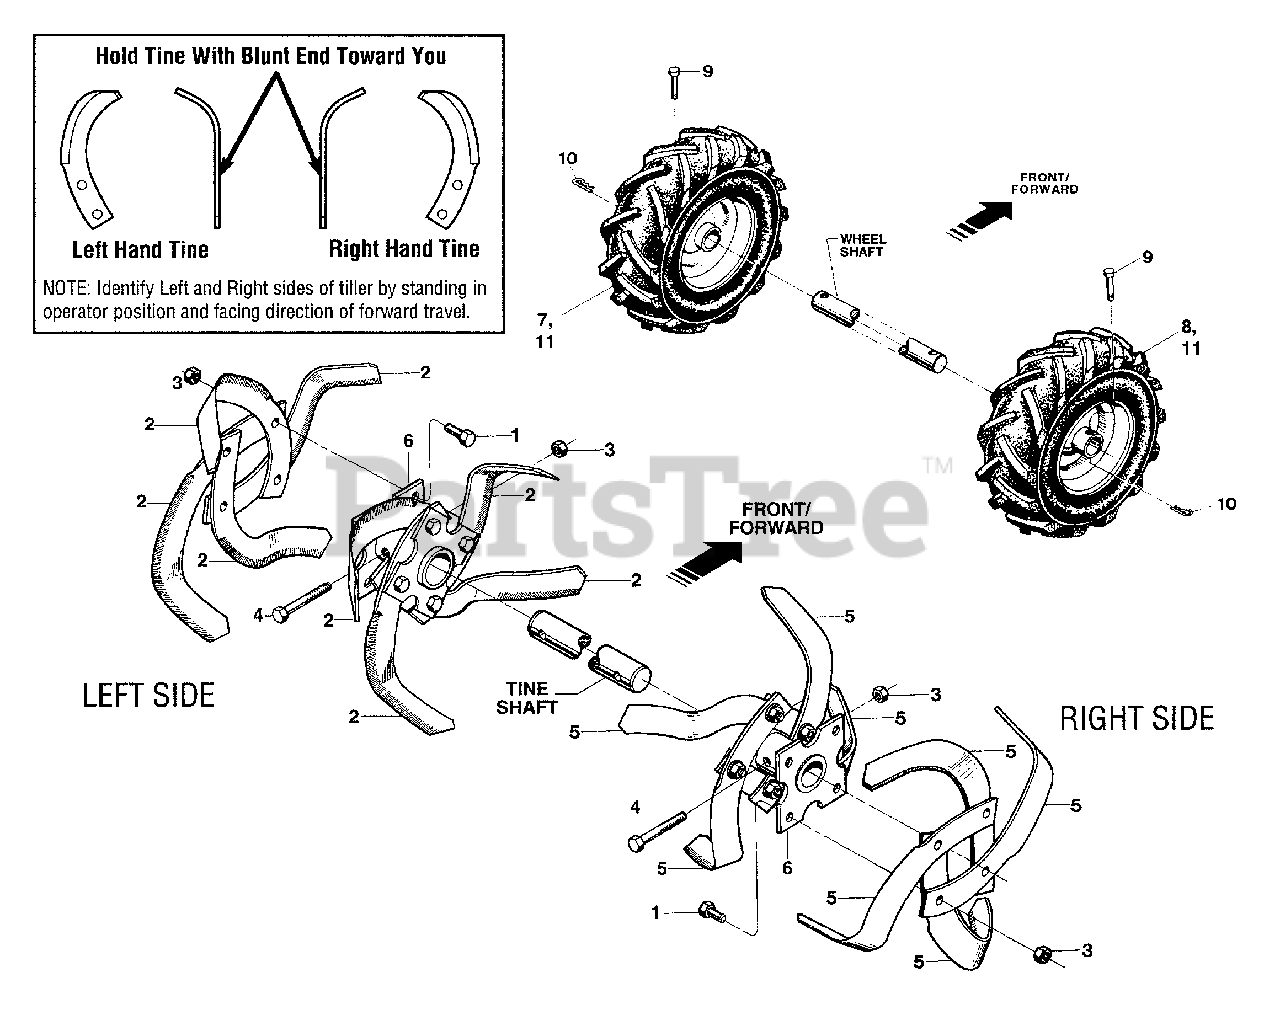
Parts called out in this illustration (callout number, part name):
1	Hex Hd. Screw, 3/8-16 x 1, Grade 5
2	Bolo Tine -
3	Hex Lock Nut, 3/8-16
4	Hex Hd. Screw, 3/8-16 x 1-3/4
5	Bolo Tine -
6	Tine Holder For Model 12208 - SN122081100101-122081199999;
7	Wheel & Tire Assy-Left Side
8	Wheel & Tire Assy-Right Side
9	Clevis Pin, .312" x 1-3/4"
10	Hair Pin Cotter
11	Wheel & Tire Assy
